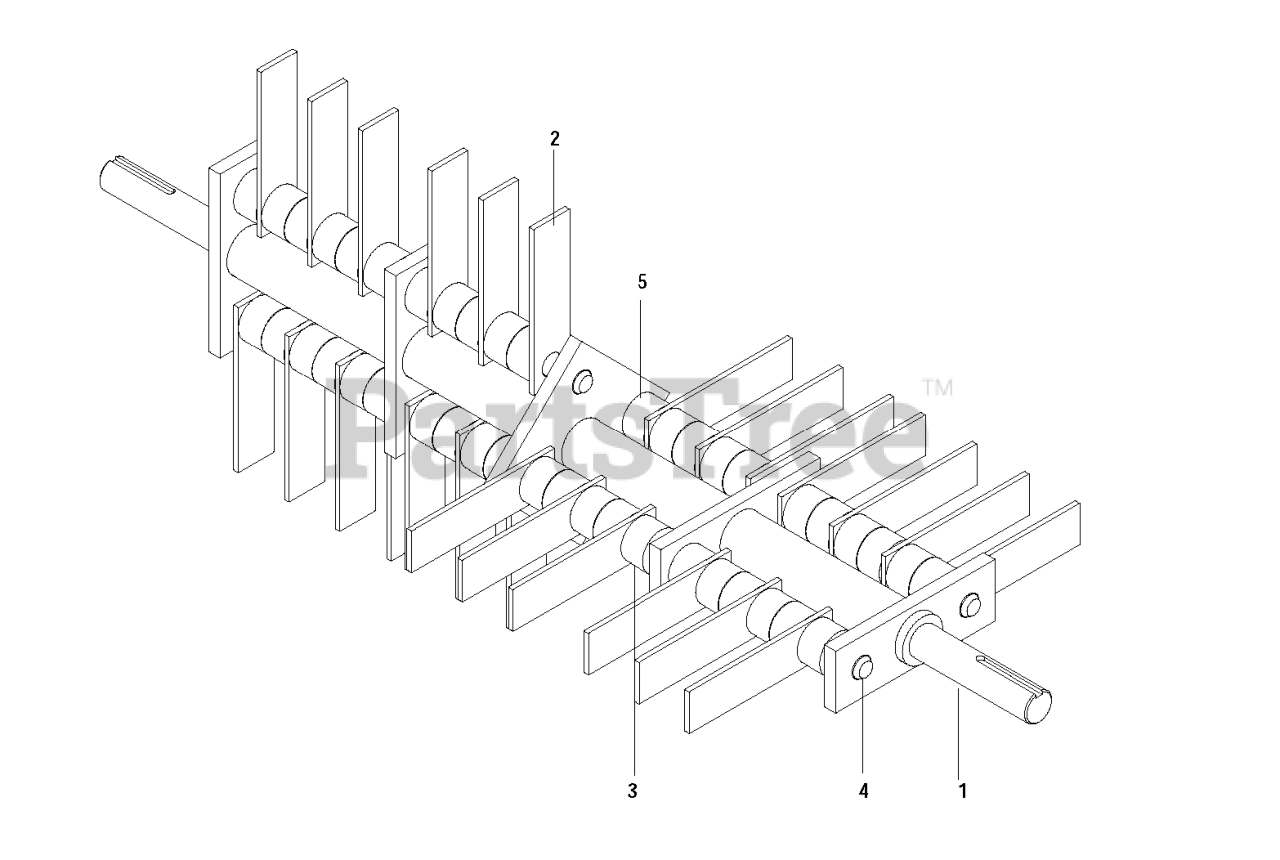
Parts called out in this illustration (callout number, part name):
1	FLAIL ASS'Y 22"
4	BLADE SHAFT
5	E-RING 1/2 (2 2)
